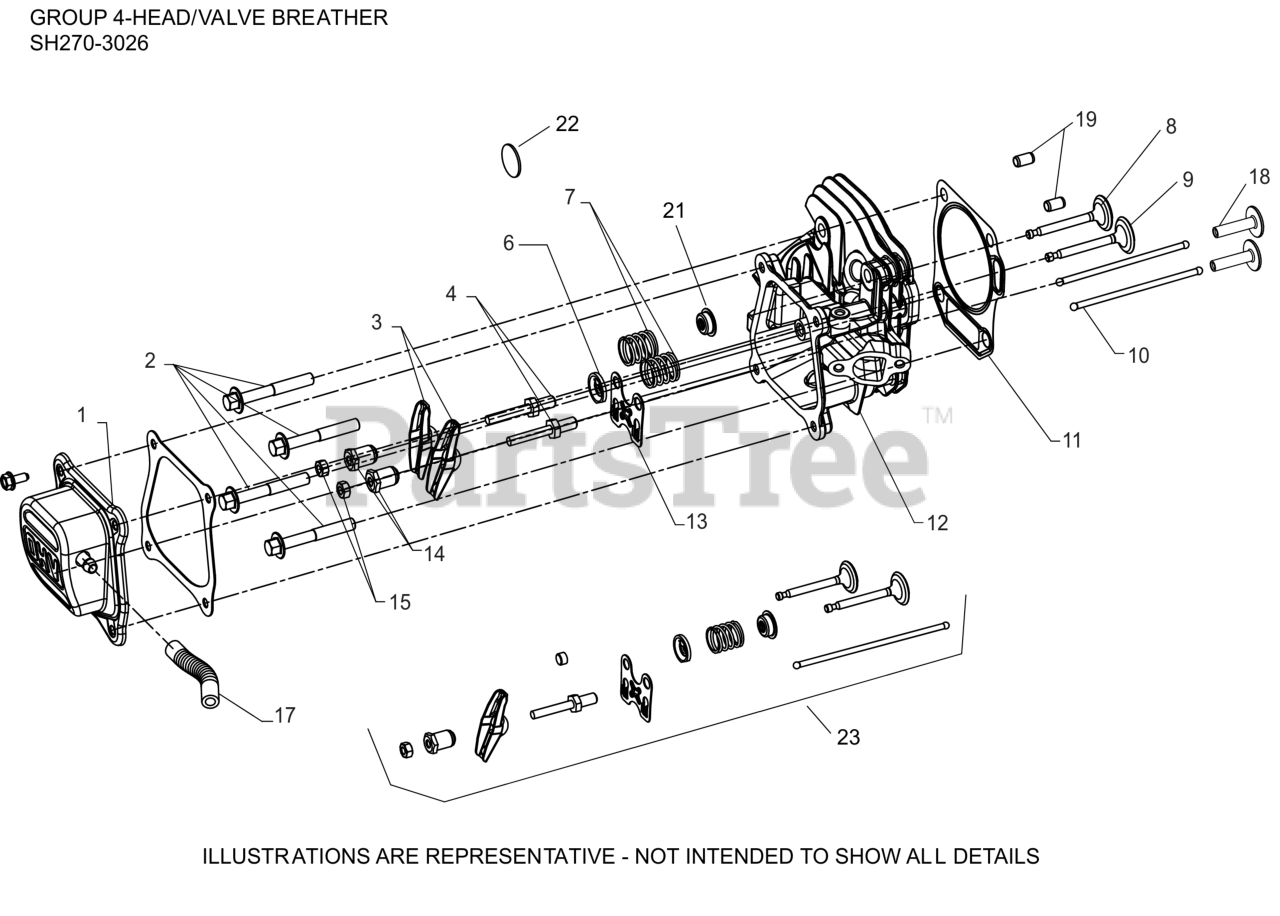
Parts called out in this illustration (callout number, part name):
1	COVER, VALVE ASSEMBLY
2	SCREW, HEX FLANGE CYL HEAD
3	ARM, ROCKER
4	STUD, ROCKER ARM-USE 14 072 22-S
6	RETAINER, VALVE SPRING
7	SPRING, VALVE
8	VALVE, EXHAUST
9	VALVE, INTAKE
10	ROD, PUSH-(#1841101S)
11	KIT, HEAD GASKET
12	HEAD ASSEMBLY, CYLINDER
13	PLATE, PUSHROD GUIDE
14	PIVOT, ROCKER ARM
15	NUT, HEX JAM
17	TUBE, BREATHER - (#1812313S)
19	PIN, DOWEL (8mm)
21	SEAL, VALVE STEM
22	REED, BREATHER
23	KIT, VALVE TRAIN
